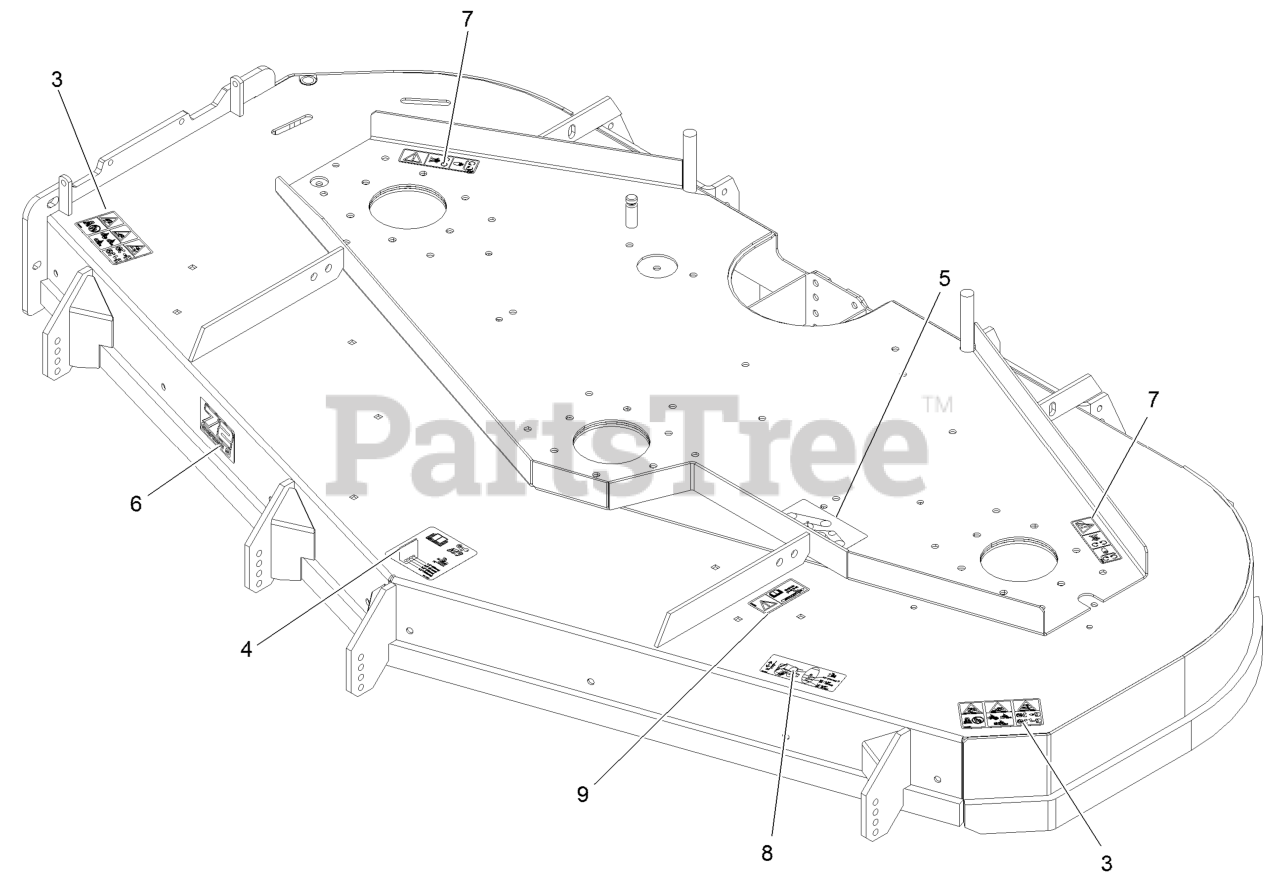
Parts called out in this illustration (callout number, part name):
3	DECAL-DANGER THROWN OBJECTS
4	DECAL-HEIGHT OF CUT
5	DECAL-BELT ROUTING
6	Decal, 725
7	DECAL-COVER, MISSING
8	DECAL-BAFFLE ADJ
9	DECAL-BOLT TORQUE
